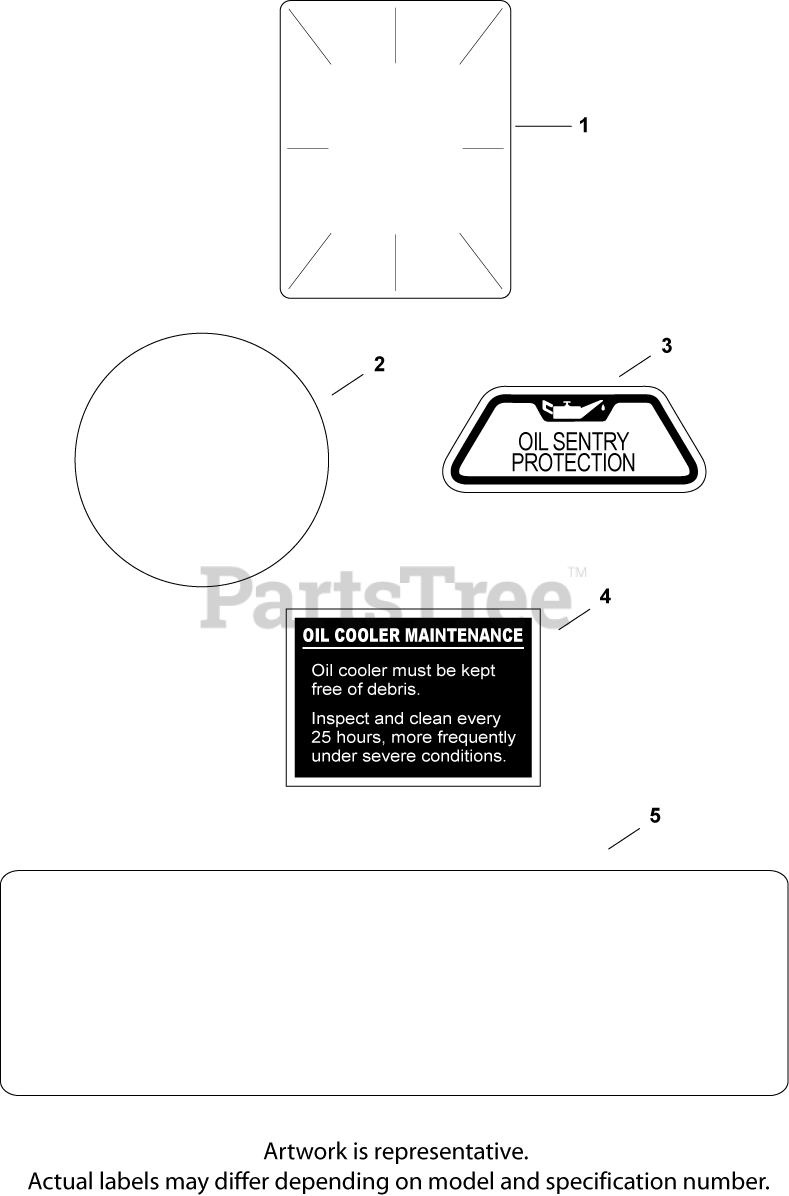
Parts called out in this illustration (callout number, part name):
1	DECAL, CLEAR LAMINITE
2	DECAL, GRASS SCREEN USE 24 113 499-S
3	DECAL, OIL SENTRY - (#DSC)
4	DECAL, OIL COOLER - (#DSC)
5	DECAL, 25 HP - DISCONTINUED
